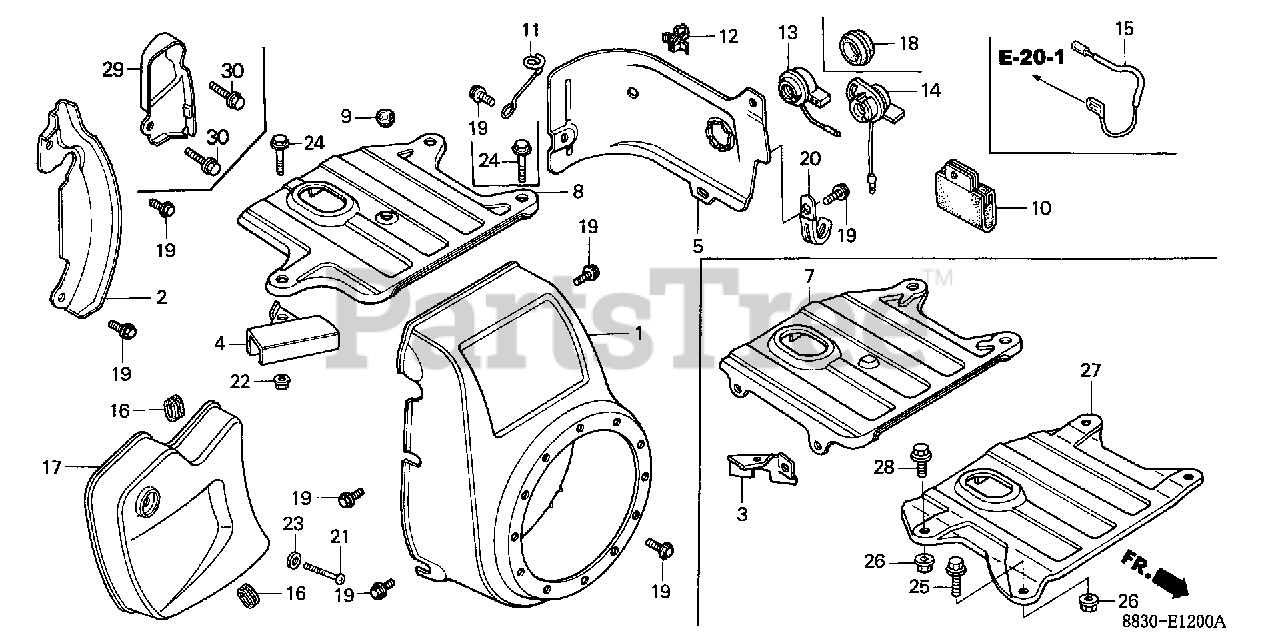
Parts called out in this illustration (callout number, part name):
1	COVER, FAN *R280* (POWER RED)
2	PLATE, SIDE
8	COVER, TOP
9	GROMMET, TOP COVER
12	CLIP, IGNITION WIRE (8MM)
13	SWITCH ASSY., ENGINE STOP
13	SWITCH ASSY., ENGINE STOP Use from Engine SN 2092216 to 2359126.
19	BOLT, FLANGE (6X12) (CT200)
20	CLIP, WIRE
